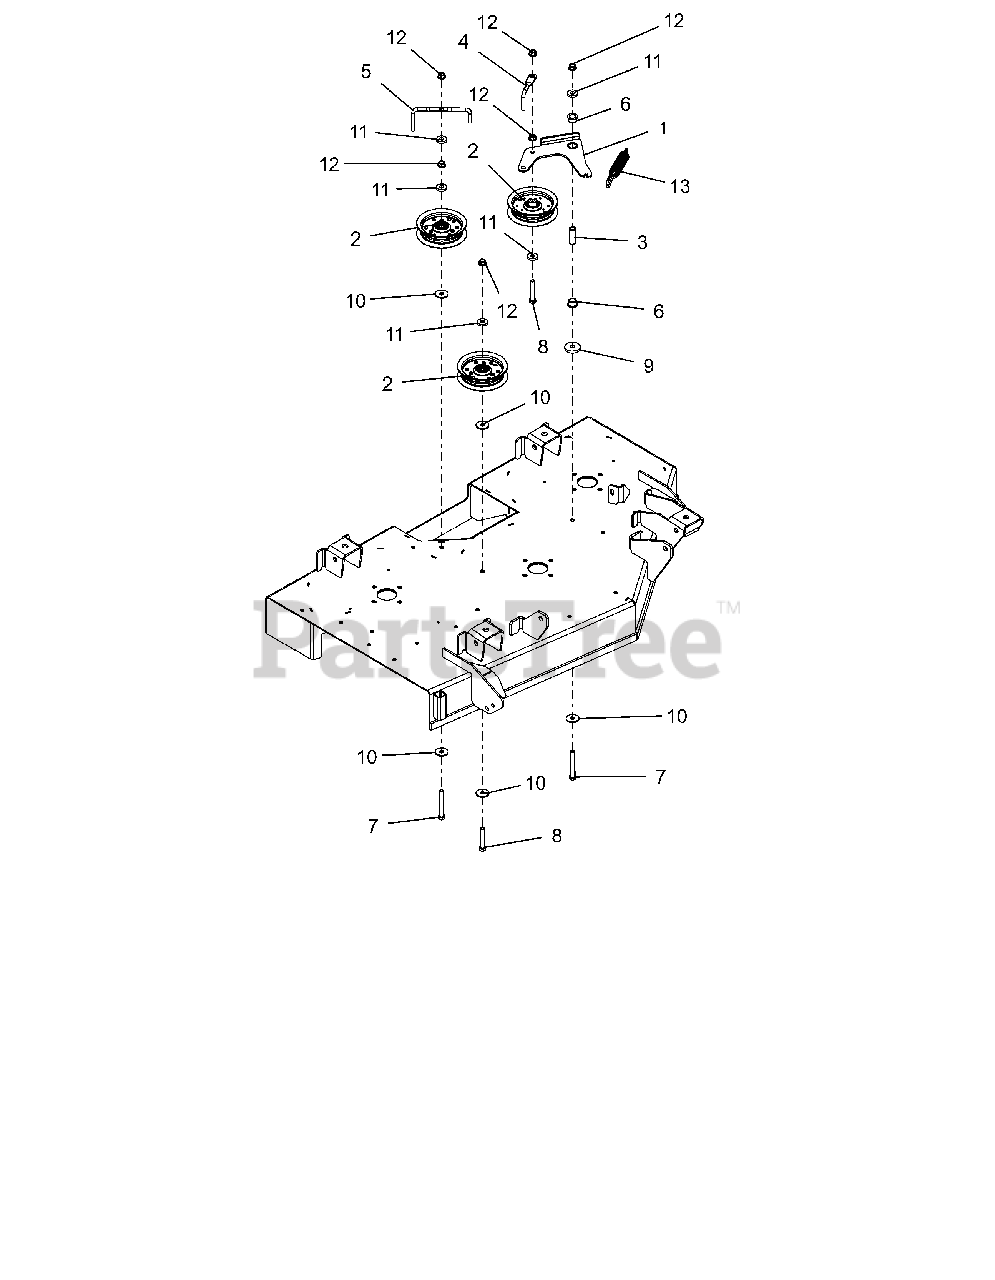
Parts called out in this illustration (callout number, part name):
1	WLDMT, IDLER ARM-42"
2	ASM, IDLER 4"
3	SPACER, .375IDX.625ODX1.66 PM
4	WIREFORM, BELT FINGER
5	WIREFORM, BELT FINGER
6	BSHG-FLG, .625X.750X.500X1.00
7	BLT-HEX .38-16X3.00 GR5 FTH YZ
8	@BLT-HEX .38-16X2.25 GR5 YWZC
9	WSHR,FLT STL.406X1.50X.245YWZC
10	WSHR FL STL .406X1.25X.10ZC120
11	WSHR-FL-STL .406X1.00X.188 YWZ
12	NUT-LK-TOP-FLG .38-16 ZC120
13	SG-TENS .135X.98X6.0 WLD 62
